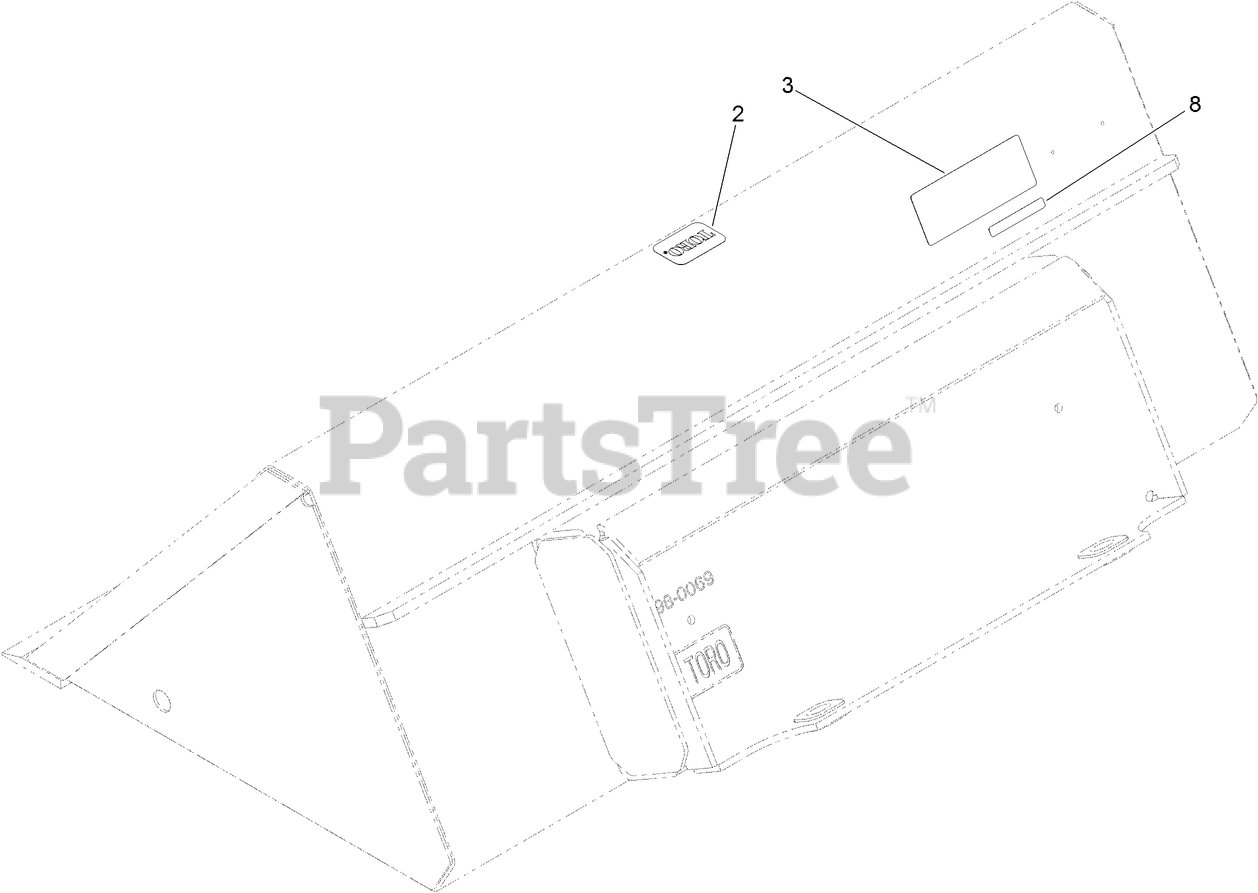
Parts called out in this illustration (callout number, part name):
2	DECAL
3	DECAL-CAPACITY
8	DECAL-WARNING
